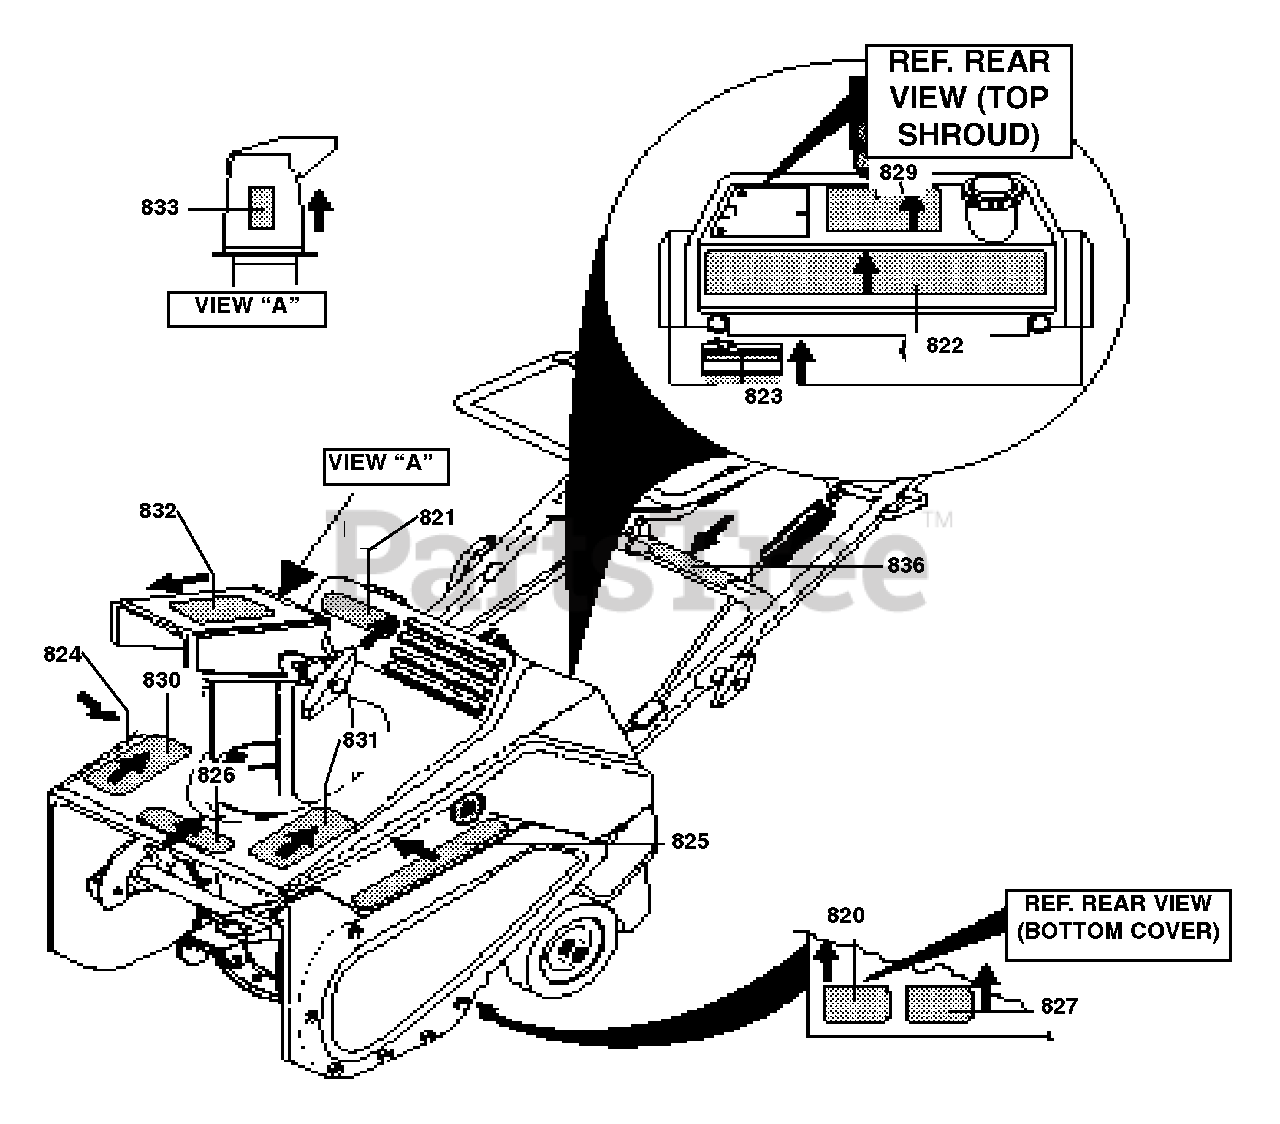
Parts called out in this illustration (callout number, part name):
821	DECAL, CROWN
822	DECAL, CONTROL PANEL
823	DECAL, CHOKE
824	DECAL, ST521E SIDE PANEL RH
825	DECAL, ST521E SIDE PANEL LH
826	DECAL, HUSQVARNA TOP COVER
827	DECAL, EPA
829	DECAL, START INSTR
830	DANGER CHUTE DECAL
831	DECAL, DANGER AUGER FOOT
832	DECAL, "CROWN" UPPRE CHT
833	DECAL, DANGER
836	DECAL, AUGER CONTROL BAR
